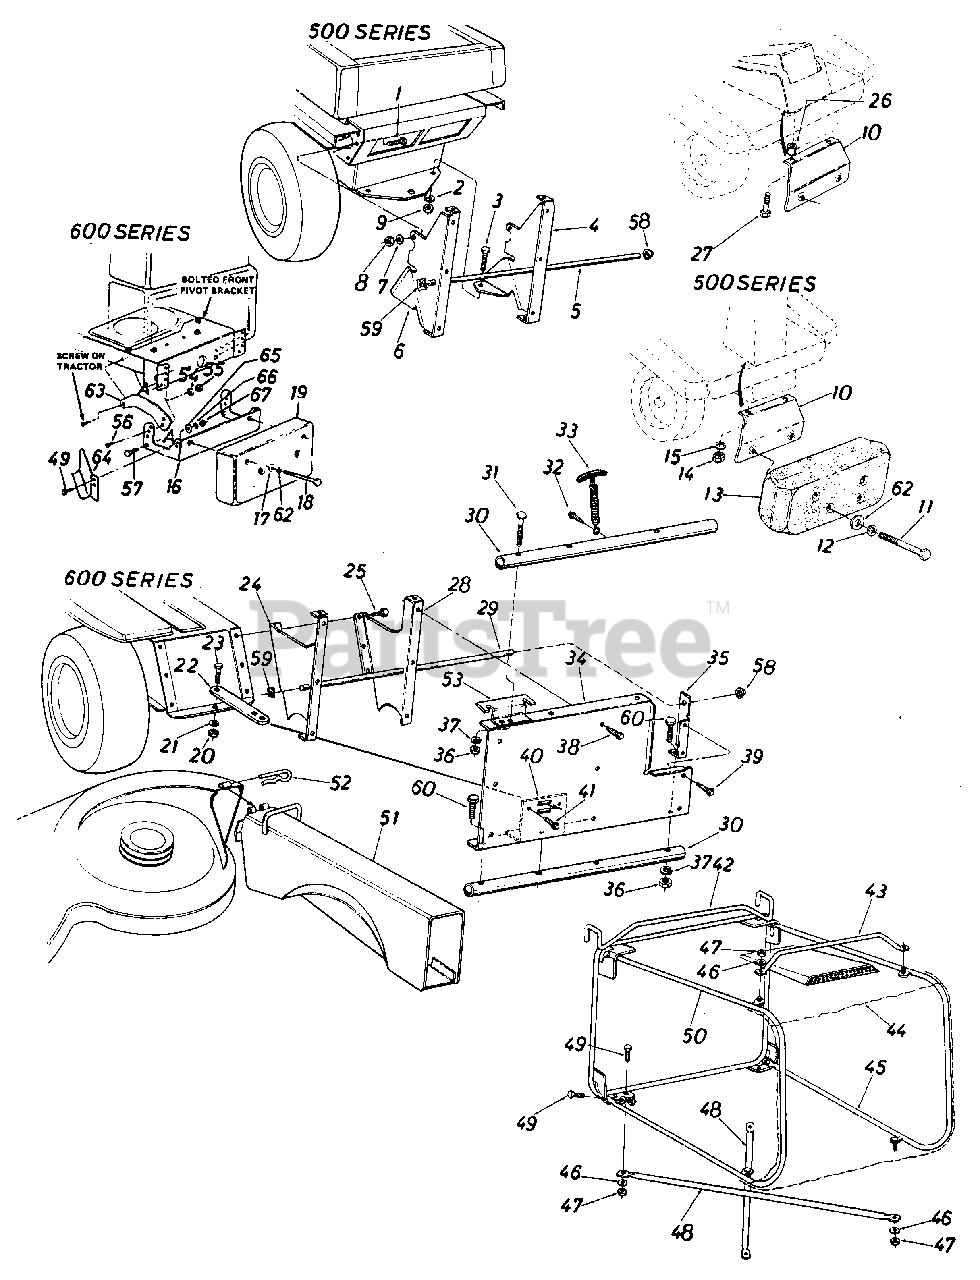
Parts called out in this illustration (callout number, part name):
1	Hex Bolt 5/16-18 x 1.00" Lg.*
2	L.-Wash. 5/16" I.D.*
3	Hex Bolt 5/16-18 x 1.00" Lg.*
4	Catcher Support Brk't-R.H.
7	L.-Wash. 5/16" I.D.*
8	Hex Nut 5/16-18 Thd.*
9	Hex Nut 5/16-18 Thd.*
10	Counterweight Bracket
11	Hex Bolt 3/8-16 x 4.5" Lg.*
12	Belleville Wash. .400" I.D. x .88" O.D.
13	Front Counterweight 38 lbs.
14	Hex Nut 5/16-18 Thd.*
15	L.-Wash. 5/16" I.D.*
16	Counterweight Bracket
17	Belleville Wash. .400" I.D. x .88" O.D.
18	Hex Bolt 3/8-16 x 4.5" Lg.*
19	Front Counterweight 38 lbs.
20	Hex Jam Nut 1/2-13 Thd.*
21	L.-Wash. 1/2" I.D.*
24	Catcher Support Brk't.-L.H.
25	Hex Wash. Hd. Self Tap Scr. 5/16-18 x .75 Lg.*
26	Spacer .380" I.D. x 1.00" O.D. x .320" Lg.
27	Not Part of Kit
28	Catcher Support Brk't.-R.H.
31	Curved Carriage Bolt 5/16-18 x 1 .75" Lg.
32	Hex "AB"-Tap Scr. 1/4" x .62" Lg.
33	Hood Latch Ass'y.
34	Grass Catcher Adapter
35	Grass Catcher Support Brk't.-R.H.
36	Hex Nut 5/16-18 Thd.*
37	L.-Wash. 5/16" I.D.*
38	Hex Wash. Hd. Self Tap Scr. 1/4-20 x .50" Lg.
39	Hex Wash. Hd. Self Tap Scr. 1/4-20 x . 50" Lg.
40	Hitch Bracket
41	Hex Wash. Hd. Self Tap Scr. 1/4-20 x .50" Lg.
42	Grass Bag Frame Ass'y.
43	Grass Catcher Handle 26.75
44	Grass Catcher Bag
47	Hex L.-Nut 1/4-20 Thd.
48	Bottom Cross Brace 30.36" Lg.*
49	Hex Bolt 1/4-20 x .62" Lg.*
52	Not Part of Kit
53	Grass Catcher Support Plate
54	L.-Wash. 7/16" I.D.*
55	Hex Nut 7/16-14 Thd.*
56	Truss Mach. Scr. 5/16-18 x .75" Lg.
57	Hex Bolt 7/16-14 x 1.00" Lg.*
58	Push Cap
59	Speed Nut
60	Bolt 5/16-18 x 1.75" Lg.*
62	Fl.-Wash. .390" I.D. x 1.12" O.D. x .187 Thk.
63	Tie Strap
64	Exhaust Deflector
65	Fl-Wash. .28" I.D. x .50" O.D.
66	L-Wash. 1/4" I.D.*
67	Hex Nut 1/4-20 Thd.*
